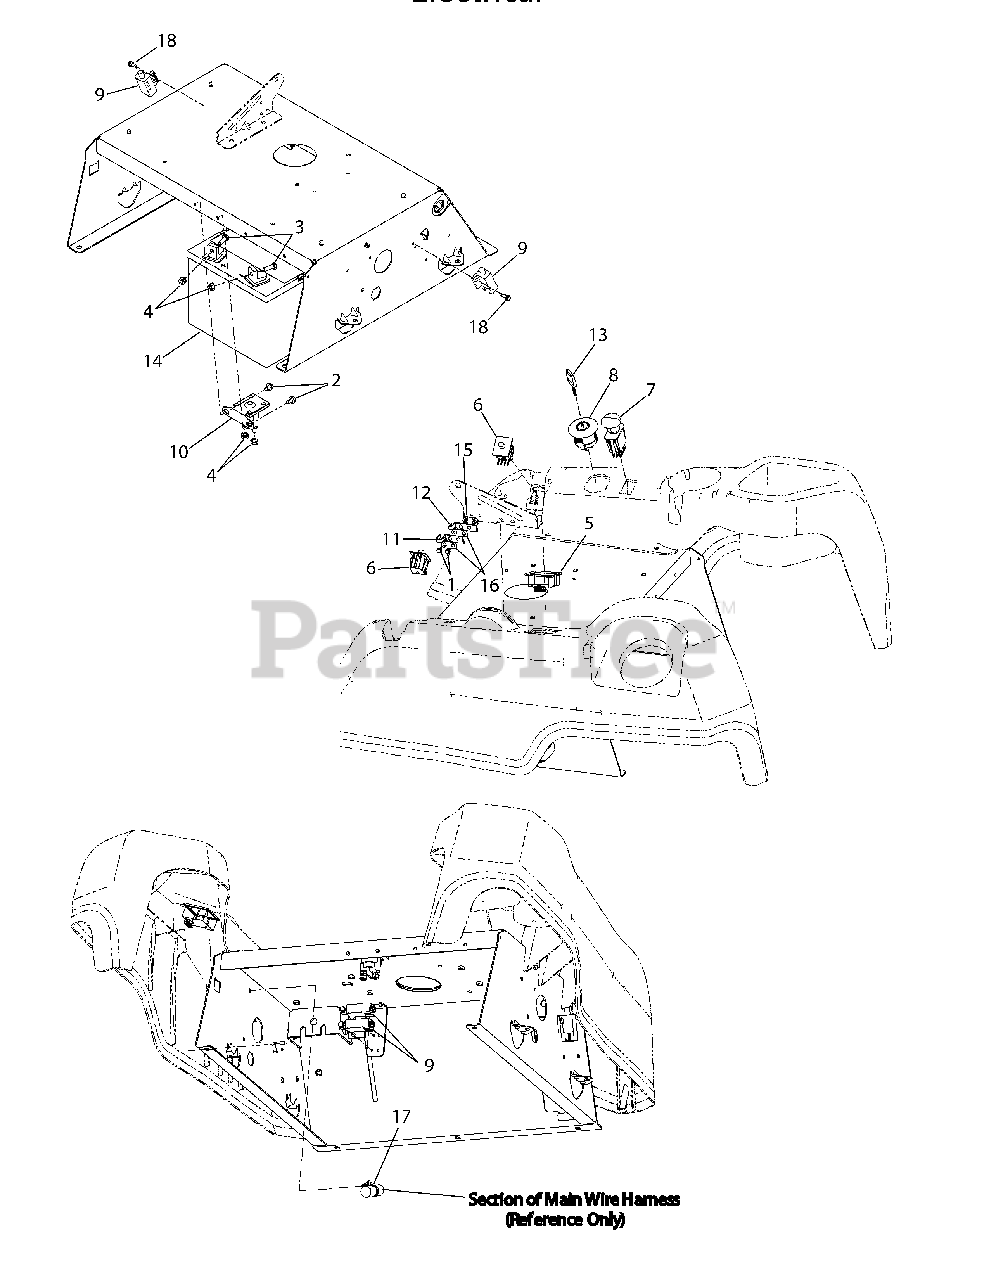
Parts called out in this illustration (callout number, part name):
1	Screw, Hex Wash. Hd. Tapp, #8-18 x .5
2	Screw, Hex Wash. Hd. Tapp, 1/4-20 x .375
3	Screw, Hex Cap, 1/4-20 x .75 GR5
4	Nut, Hex Sems, 1/4-20
5	Meter, Hour
6	Switch, Dbl. Pole - Neutral
7	Switch, PTO
8	Switch, Ignition
9	Switch, Interlock, (NO/NC) - Brake/Rev
10	Solenoid
11	Switch, Outer Seat Spring
12	Switch, Inner Seat Spring
13	Key
14	Battery, 235 CCA
15	Plate, Insulator Boss
16	Plate, Insulator
17	Tie, Cable
18	Screw, Shoulder, #10-32 x .5
